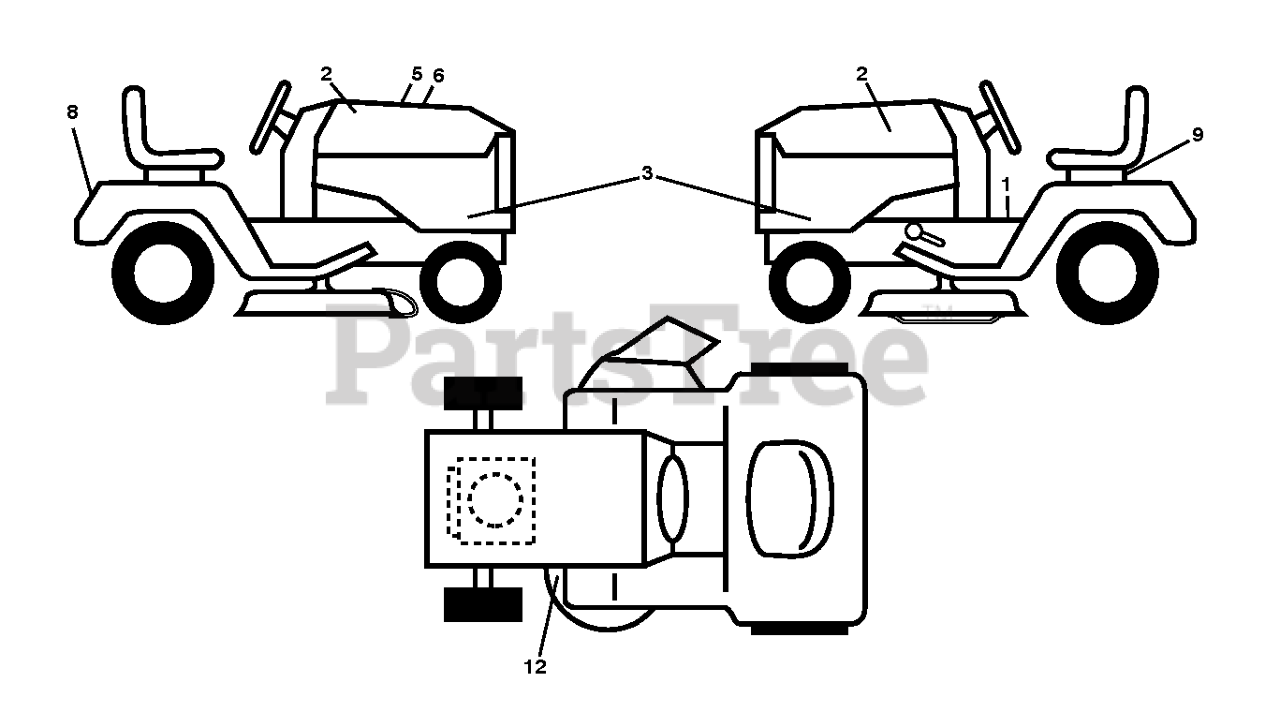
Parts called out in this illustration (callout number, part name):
1	DECAL.WARN.START.INSTRUCTIONS
2	DECAL.BADGE.170MM.TEXTLOGO.
3	RP DECAL.PNL.SD.YTH21K46.HUSQ
5	DECAL.WARNING.CUST.RESP.E85.
6	DECAL.REPLACEMENT.960450026
8	DECAL.FENDER
9	DECAL BTRY SYMBOLS
12	DECAL V BELT SCHEMATIC
